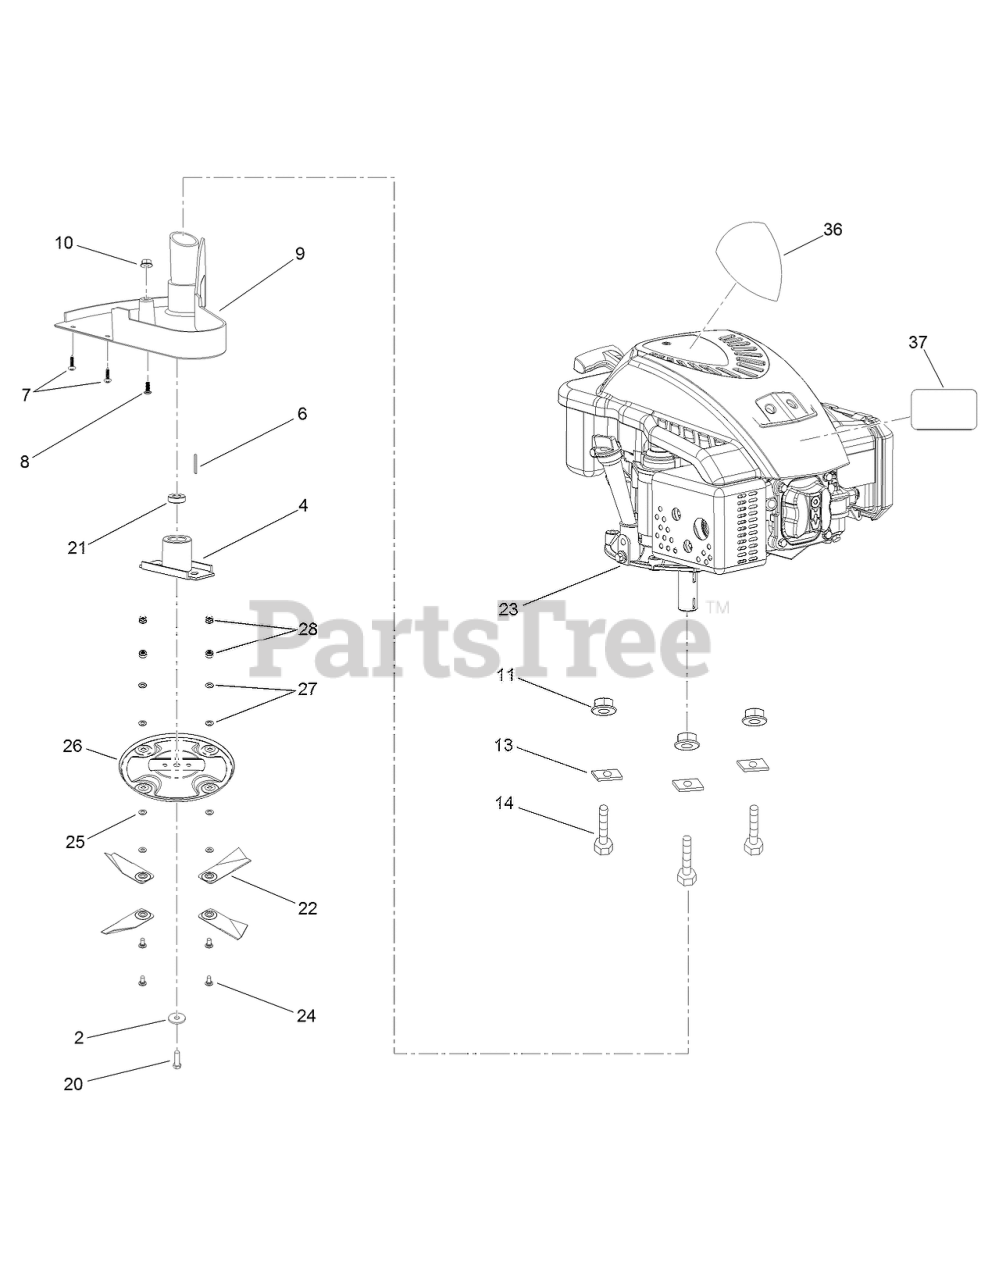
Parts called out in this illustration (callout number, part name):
2	WASHER-DISHED
4	SUPPORT-BLADE
6	KEY-FLAT
7	SCREW-SELF DRIVING
8	SCREW-TOOTH
9	COVER-PULLEY, BELT
10	NUT-LOCK, FLANGE
11	NUT-LOCK, FLANGE
13	WASHER-SQUARE
14	SCREW-HH
20	BOLT-BLADE
21	SHEATH-BLADE
22	BLADE-SWING
23	ENGINE-1P65FA, RECOIL
24	BOLT-BLADE, SWING
25	WASHER-FLAT
26	SUPPORT-BLADE, SWING
27	WASHER-BLADE, SWING
28	NUT-LOCK
36	DECAL-SHROUD
37	PLATE-LOGO
